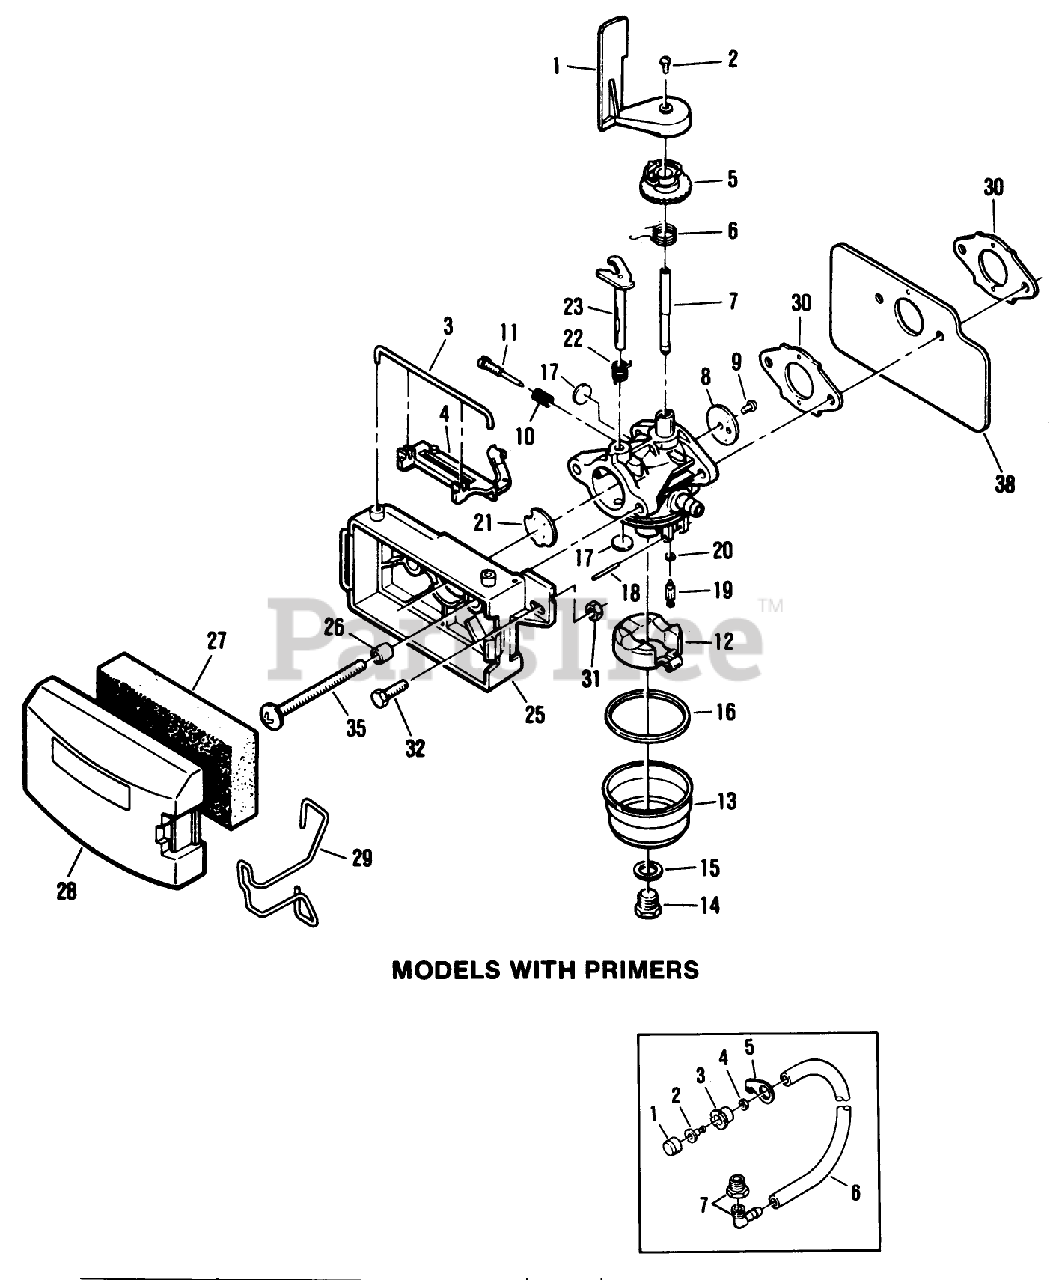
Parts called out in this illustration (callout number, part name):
1	AIR VANE F
2	SCREW F
3	RETAINER
5	COLLAR A/VAVE F
7	Shaft-Throttle
8	Valve-Throttle
9	Screw-Throttle Valve
10	Spring-Idle Needle
11	Needle-Idle
13	Bowl-Fuel
14	Screw-Bowl Retainer Kit-Gasket
15	Gasket-Bowl Retainer
16	Gasket-Fuel Bowl
17	Plug-Welch
18	Shaft-Float
19	Valve-Inlet Needle
20	Seat-Valve Kit-Gasket
21	Valve-Choke
22	Spring-Choke Return
23	Shaft-Choke
26	SPACER
29	RETAINER-COVER, FILTER
30	GASKET CARB S
32	Screw (Throttle Cable)
35	SCREW
